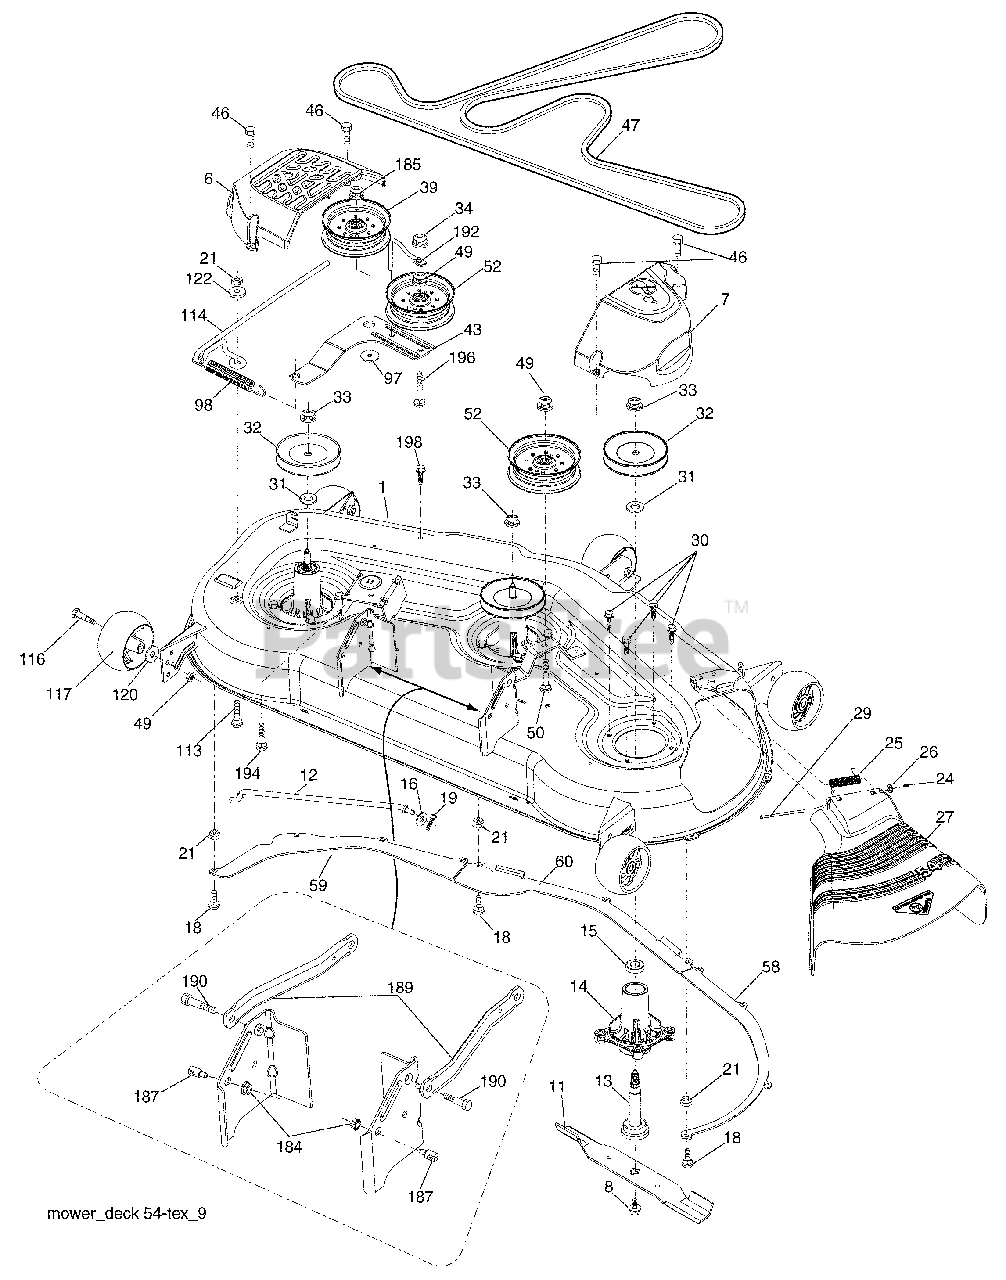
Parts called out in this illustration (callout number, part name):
1	Deck Weldment Mower
6	Cover Mandrel LH
7	Cover Mandrel RH
8	Bolt 7/16 Asm. Blade
11	Blade Discharge
12	Bar Anti-Sway
13	Shaft Asm. w/Lower Bearing
14	Housing, Mandrel
15	Bearing, Ball, Mandrel
16	Washer 3/8
18	Bolt RdHd 5/16-18 unc x 5/8
19	Pin Cotter 5/16 Bowtie
21	Nut, Crownlock 5/16-18 unc
24	Cap Sleeve
25	Spring, Torsion
27	Deflector Shield
29	Rod, Hinge
30	Screw, Thdroll Washer Head
31	Washer, Spacer Mower Vented
32	Pulley, Mandrel
33	Nut, Flg. Top Lock
34	Nut Crownlock 3/8-46 UNC
39	Pulley, Idler, LH
43	Arm, Idler
46	Screw, Thdroll. 1/4-20 x 5/8
47	Belt Deck Drive
49	Nut, Lock Flg. 3/8-16 unc
50	Bolt Carriage 3/8-16 x 2 Gr. 5
52	Pulley Idler
58	Baffle Right
59	Baffle Left
60	Baffle Center
97	Washer Hardened
98	Spring Drive
113	Bolt Rdhd Sqnk 5/16-18 x 3/4
114	Rod Tension Relief
116	Bolt, Shoulder
117	Gauge Wheel
120	Washer 13/32 x 1-1/4 x 12 Ga.
122	Bushing Tension Relief
184	Nut Lock Hex Flange
185	Nut Lock Flange 7/16-14 Gr. 5
187	Stud Fastener w/"D" Anti-Rotation
189	Arm Susp. Mower Rear
190	Bolt Shoulder
192	Keeper Belt Idler
194	Bolt Carr Sqnk 7/16-24 x 2
196	Bolt RDHD SQNK 3/8-16 x 2-1/2 Gr.5
198	Screw 3/8-16 x 1/2
